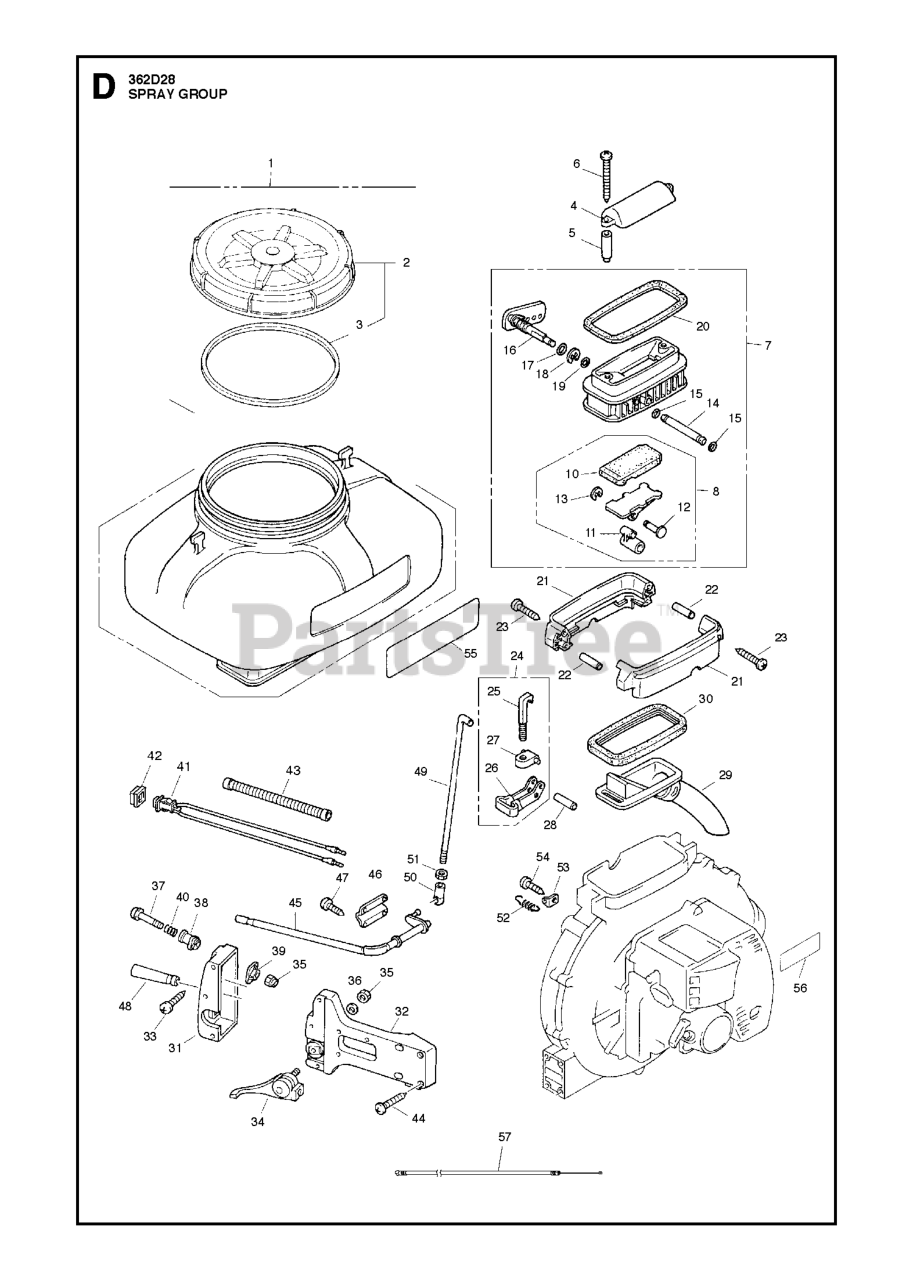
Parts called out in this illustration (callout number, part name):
8	SHUTTER ASSY
36	WASHER
42	CAP SWITCH
